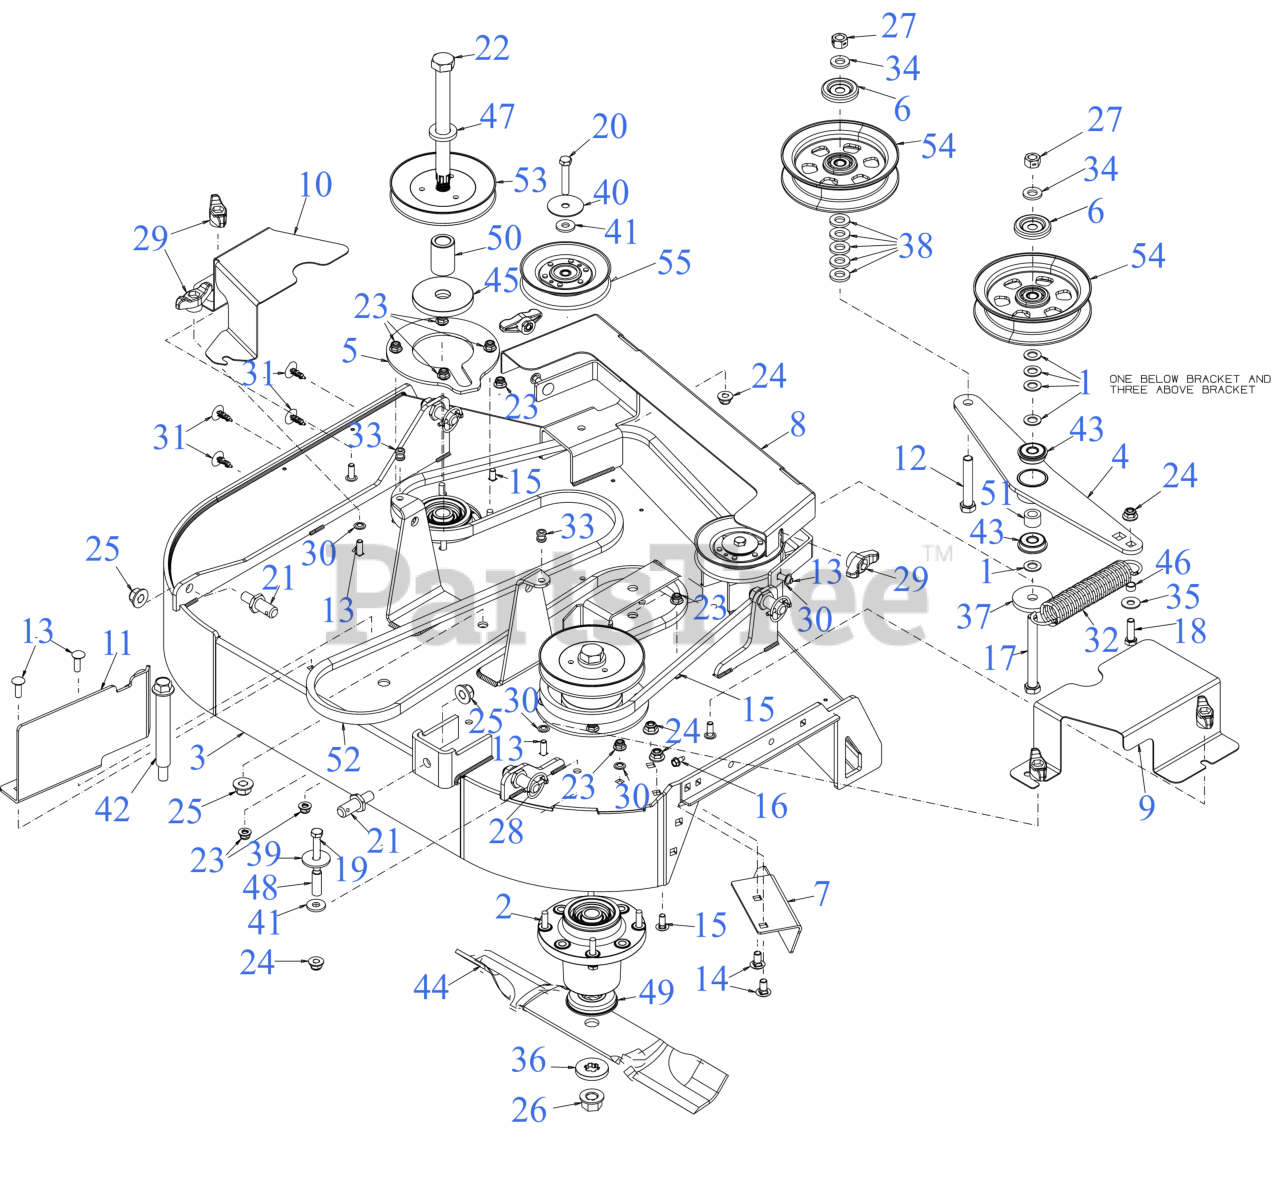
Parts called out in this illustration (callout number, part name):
1	THRUST WASHER
2	SPINDLE ASSEMBLY
3	36" DECK
4	IDLER ARM ASSEMBLY
6	PULLEY CAP
8	DECK BELT COVER
9	DECK BELT COVER (RH)
10	DECK BELT COVER (LH)
11	BELT KEEPER BRACKET
12	SCREW-HEX 1/2-13 x 3.00
13	CARRIAGE BOLT 5/16-18 x 1.00
14	CARRIAGE BOLT 3/8-16 x .750 GR5
15	CARRIAGE BOLT 5/16-18 x .75
16	SCREW 1/4-20 X.500
17	SCREW 1/2-13 x 4.5 GR 5
18	SCREW 3/8-16 x 1.25 GR5
19	SCREW 3/8-16 x 2.25 GR5
20	SCREW 3/8-16 x 2 GR5
22	SPINDLE SHAFT 8.12"
23	FLANGE LOCK NUT 5/16-18
26	FLANGE NUT - 5/8-18 GDE 8
27	HEX NUT CTR LK 1/2-13
28	LYNCH PIN .1875
29	WING KNOB 5/16-18
31	RATCHET CLIP
32	EXTENTION SPRING
34	FLAT WASHER .510 x 1.000 x .125
35	WASHER-.395 x 1.0 x .62
36	FLAT WASHER - SPECIAL
37	FLAT WASHER .53"x2.125"x.25"
38	FLAT WASHER .531X1.060X.134
39	FLAT WASHER .406X1.500X.105
40	HUB CAP WASHER .406 x 1.92 x .060
41	FLAT WASHER .406ID X1.0 OD
42	SHOULDER BOLT .750X4.75X1/2-13
43	ROLLER BEARING .5X1.37X.44
44	18.50" BLADE (HI LIFT)
45	DECK SPINDLE SPACER
47	SPACER .812 ID x .218 LG
49	SPACER 0.790 x 2.75 x 0.486
50	SPACER .80X1.25X1.878
51	SPACER .51X.88X.575
52	DECK BELT B-SEC x131.1"
53	SPINDLE PULLEY (5.625")
54	5" FLAT IDLER PULLEY
55	IDLER PULLEY 5.06"
